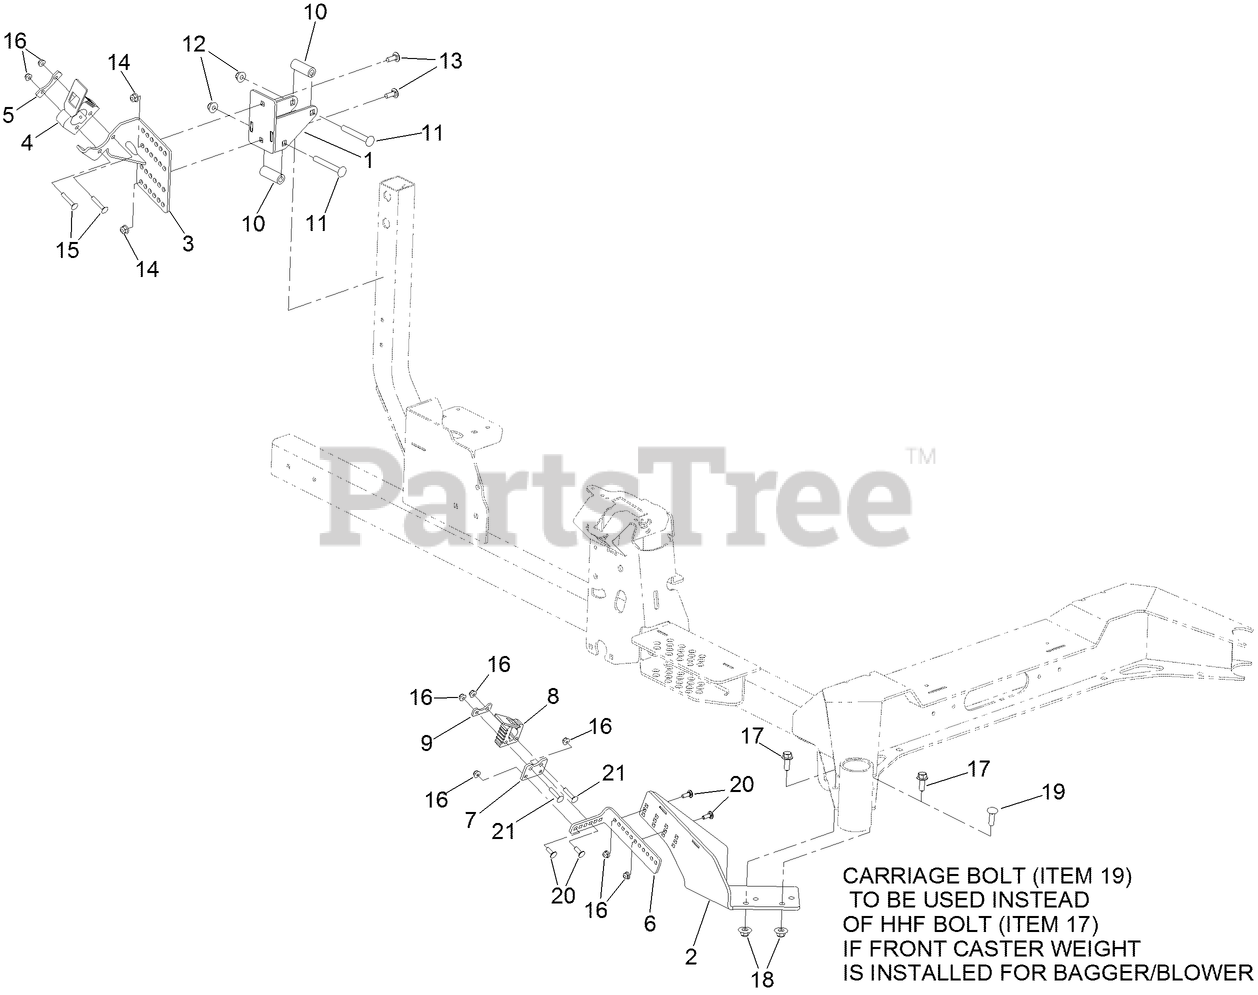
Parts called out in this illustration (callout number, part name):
1	UPPER MOUNT [BLACK]
2	LOWER MOUNT [BLACK]
3	BRACKET-MOUNT, UPPER TRIMMER
4	CLAMP-QUICK FIST, ORIGINAL
5	PLATE-BACKER, LARGE
6	BRACKET-MOUNT, TRIMMER
7	PLATE-MOUNT, QUICK FIST
8	CLAMP-QUICK FIST, MINI
9	PLATE-BACKER, SMALL
10	SPACER-TUBE
11	SCREW-CARR
12	NUT-HF, NI
13	BOLT-CARR
14	NUT-HF, NI
15	SCREW-CARR
16	NUT-HF
17	SCREW-HHF
18	NUT-FLANGE, NI
19	SCREW-CARR
20	BOLT-CARR
21	SCREW-CARR
